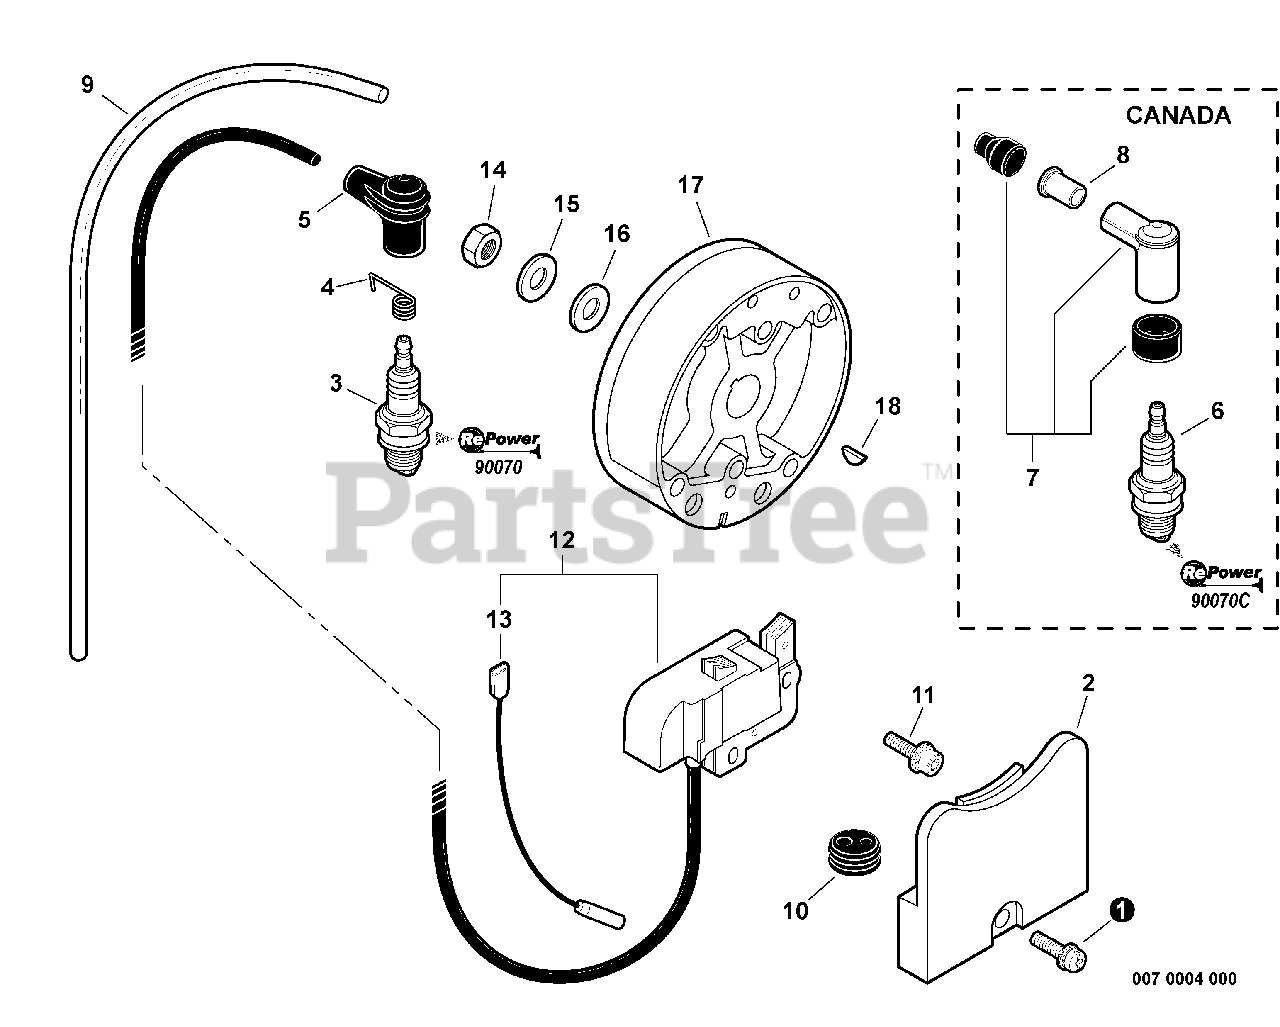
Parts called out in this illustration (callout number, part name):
1	SCREW - 5X22
2	COVER, DUST
3	SPARK PLUG -- BPM-8Y
4	TERMINAL, SPARK PLUG CAP
5	CAP, SPARK PLUG
6	SPARK PLUG -- BPMR-8Y
7	CAP, SPARK PLUG
8	ADAPTER, SPARK PLUG CAP
9	TUBE - VINYL
11	SCREW - 5X22
12	IGNITION COIL KIT
13	LEAD - IGNITION
14	NUT - 10
15	LOCKWASHER - 10
16	WASHER - 10
17	FLYWHEEL
18	KEY - 3X14
19	RePower TUNE-UP KIT
20	RePower TUNE-UP KIT
